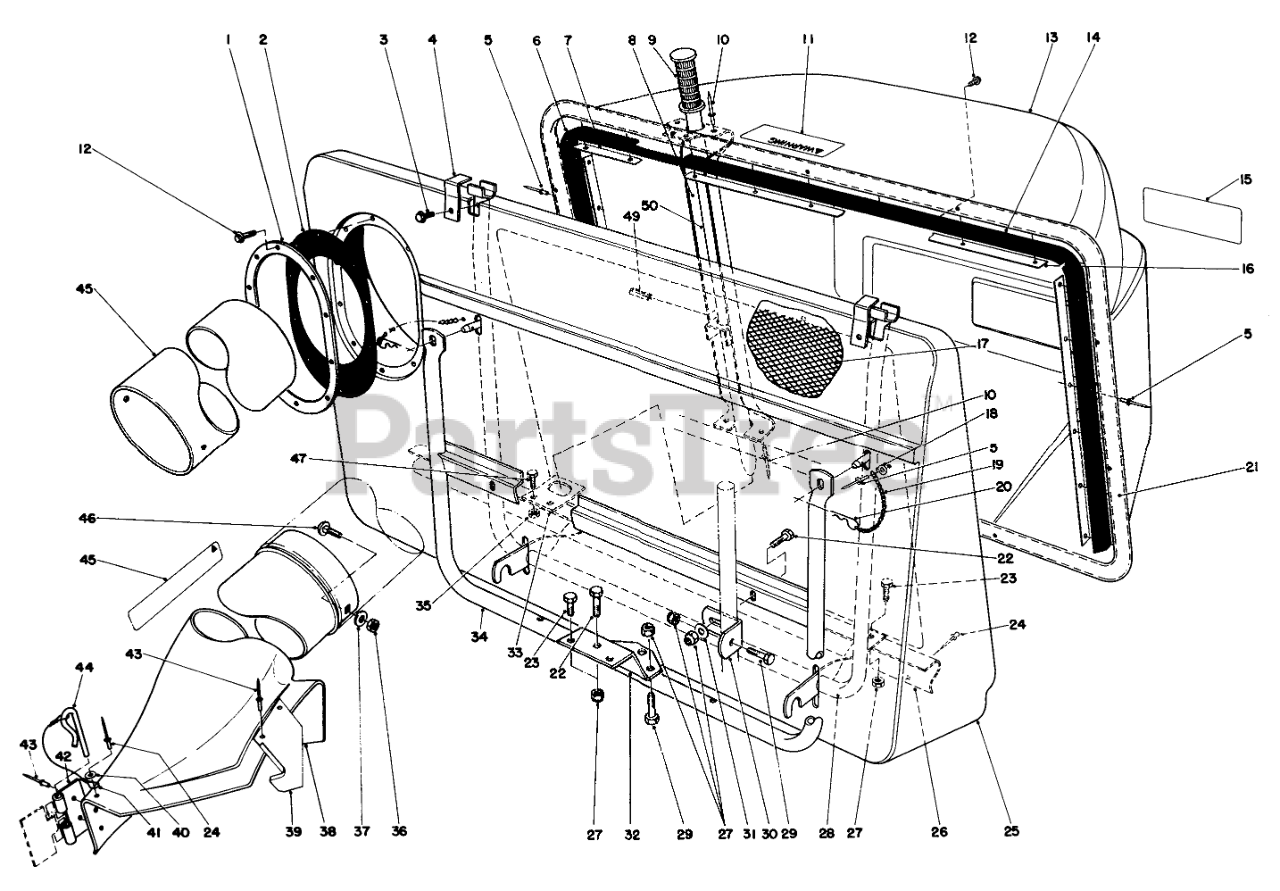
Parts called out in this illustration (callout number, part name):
1	RING-RETAINING
2	RING-RETAINER, RUBBER
3	SCREW-HWH
4	RETNR PIVOT BRKT
6	RH BAG SEAL
7	RETNR TOP EXT.
8	DUMP HDLE CHANL WA
11	DECAL
12	SCREW-HWHTF
13	REAR GRASS BASKET
14	Seal-Bag LH.
15	EASY EMPTY BAG DECAL
16	BAG RETNR EXT.
17	Screen Bag
18	WASHER
19	10 LINK CHAIN W/O HOOK
20	PIN-HAIR
21	BAG SUPT ASM FRM
22	SCREW-HH
23	SCREW-HH
24	RIVET-BLIND
25	Bag Front
26	FRAME SUPT BRKT B
27	NUT-LOCK, CONE
28	Bag Frame
29	SCREW-HH
30	Bracket Mtg. Grass Catcher
31	WASHER-PLAIN
32	Plate-Mtg. Grass Catcher
33	Hanger-Frame Lower
34	BAG SUPPORT WA
35	NUT-LOCK, CONE
36	NUT-KEPS
37	WASHER-FLAT
38	Chute Assembly (Incl. Ref. #24, 39-45)
39	CHUTE SUPT BRKT
40	WASHER-PLAIN
41	LANYARD
42	BRACKET-MOUNTING, CHUTE
43	RIVET-BLIND
44	PIN-LOCKING, CHUTE
45	Decal-Chute
46	BOLT-CARR
47	SCREW-HH
48	Duct
49	PIN-ROLL
50	DUMP HANDLE ASM
